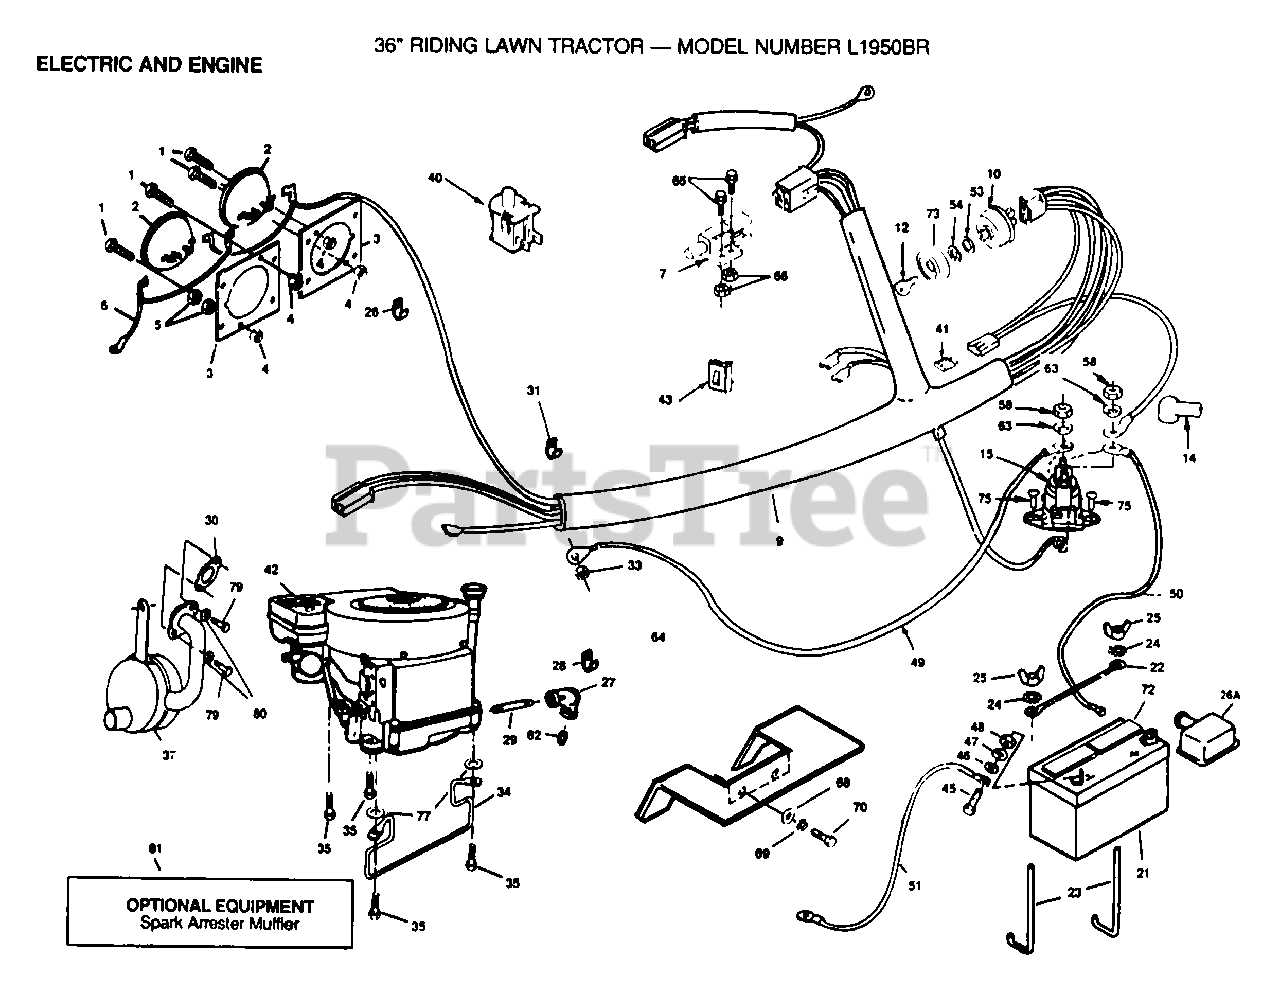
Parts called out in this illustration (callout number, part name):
7	SWITCH INTERLOCKT
8	SCREW
11	LOCKWASHER
22	"ROD, BATTERY"
23	"BOLT, BATTERY"
24	LOCKWASHER GT
26	CLIP SB
27	ELBOW
28	INSUL CLIP T
29	PIPE NIPPLE
34	BELT KEEPER LT
35	SCREW LT
40	SWITCH SEAT
41	FUSE HYT
42	ENGINE 12 H.P. TYPE 0201-01
43	SWITCH LT
45	BOLT LT
46	WASHER
47	LOCKWASHER
49	"CABLE T, BATTERY"
53	WASHER T
58	NUT
62	PLUG OIL DRAIN
64	SHIELD HEAT LT
65	SCREW
66	"NUT,KEPS"
69	LOCKWASHER
72	"CAP,BATTERY "
75	"SCREW,MACHINE"
77	WASHER
79	BOLT
80	LOCKWASHER
